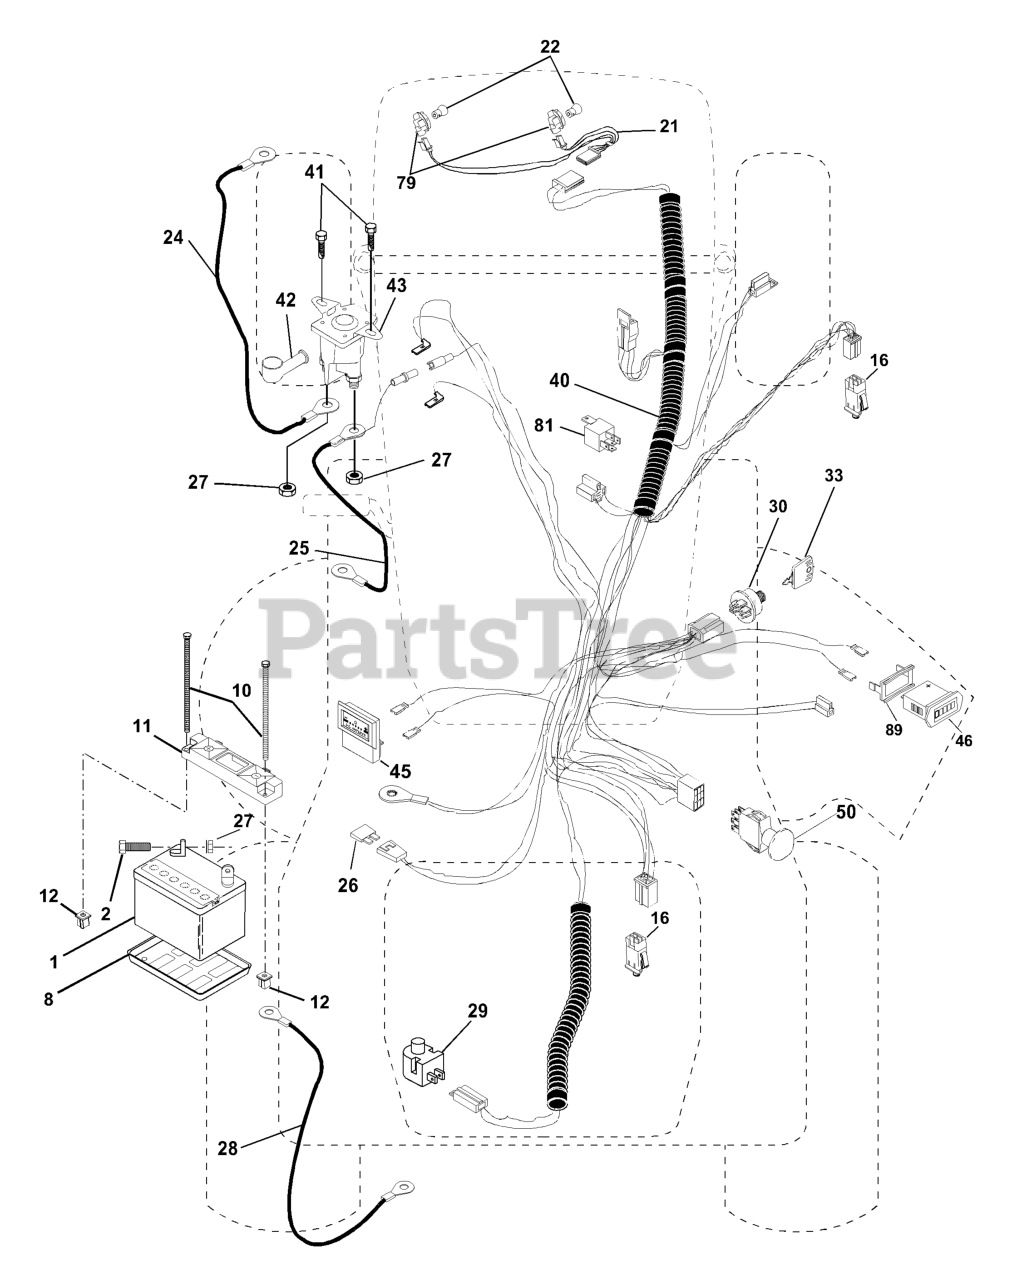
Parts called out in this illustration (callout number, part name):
1	BATTERY
2	BOLT.HEX.1/4.X.3/4.DICHROMATE
8	BATTERY TRAY T
10	BOLT 1/4-20 X 7.5
11	BATTERY HOLDDOWN FRONT MOUNT
12	NUT, PUSH NYLON 1/4" BATTERY
16	SWITCH INTERLOCK
21	HARNESS ASM LIGHT
24	HIGH SPEED GEAR
25	CABLE, BATTERY
27	NUT
28	CABLE, GROUND
29	PLUNGER SWITCH (COLOR:OLIVE)
30	IGNITION SWITCH
33	KEY MLD GEN DELTA
40	HARNESS, IGNITION
41	SCREW
42	TERMINAL COVER
43	REPL BY 532 1461-54
46	HOUR METER
50	RP.PTO.SWITCH.8 TERMINAL.BLACK
79	BULBHOLDER ASM
81	RELAY.ASSY.T
89	BRACKET SNAP-IN HOURMETER
